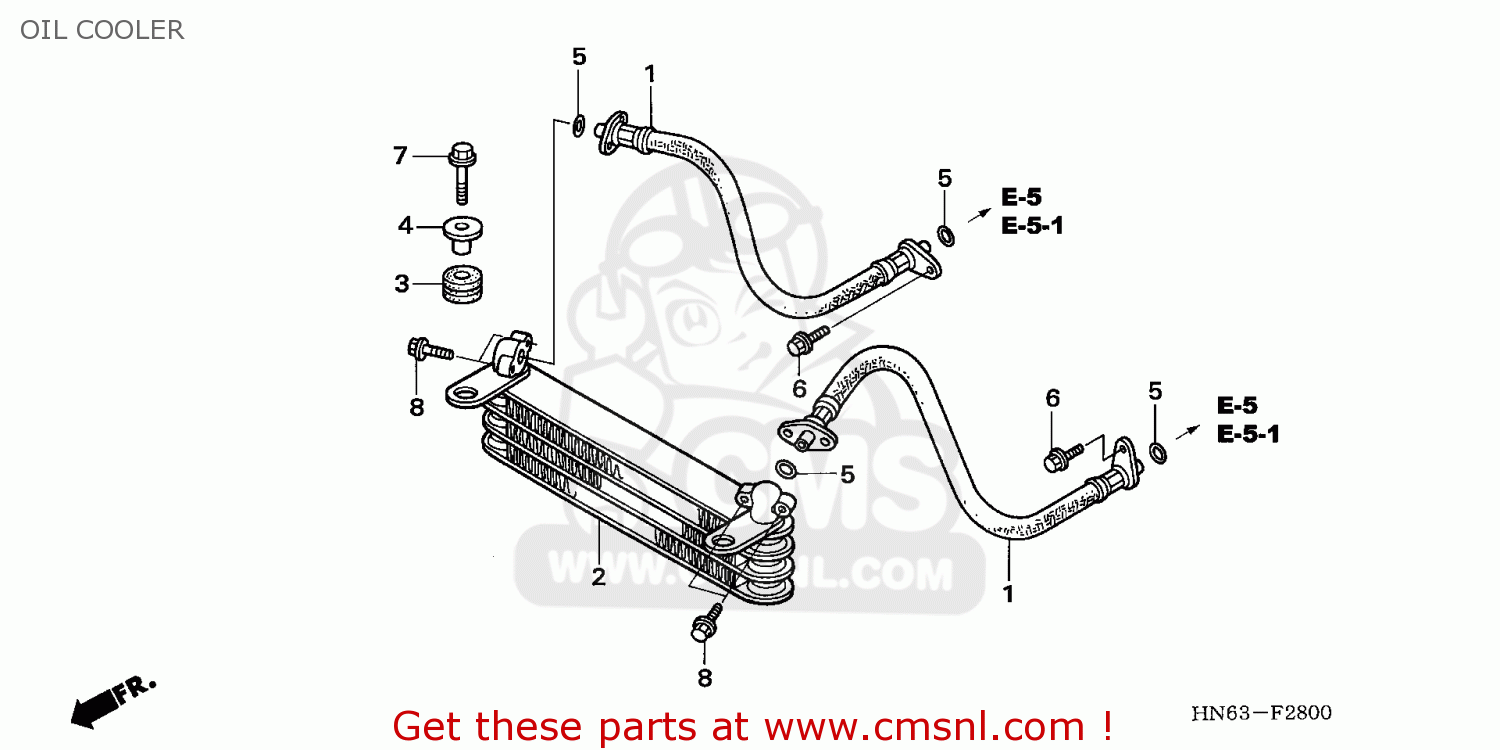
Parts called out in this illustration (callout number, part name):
1	HOSE COMP R,OIL
2	COOLER COMP,OIL
3	RUBBER,RAD.MOUNT
4	COLLAR,RAD MT
5	O-RING 11X2.4
6	BOLT FLANGE 6X18
7	BOLT,FLANGE,6X22
8	BOLT FLANG 6X20
